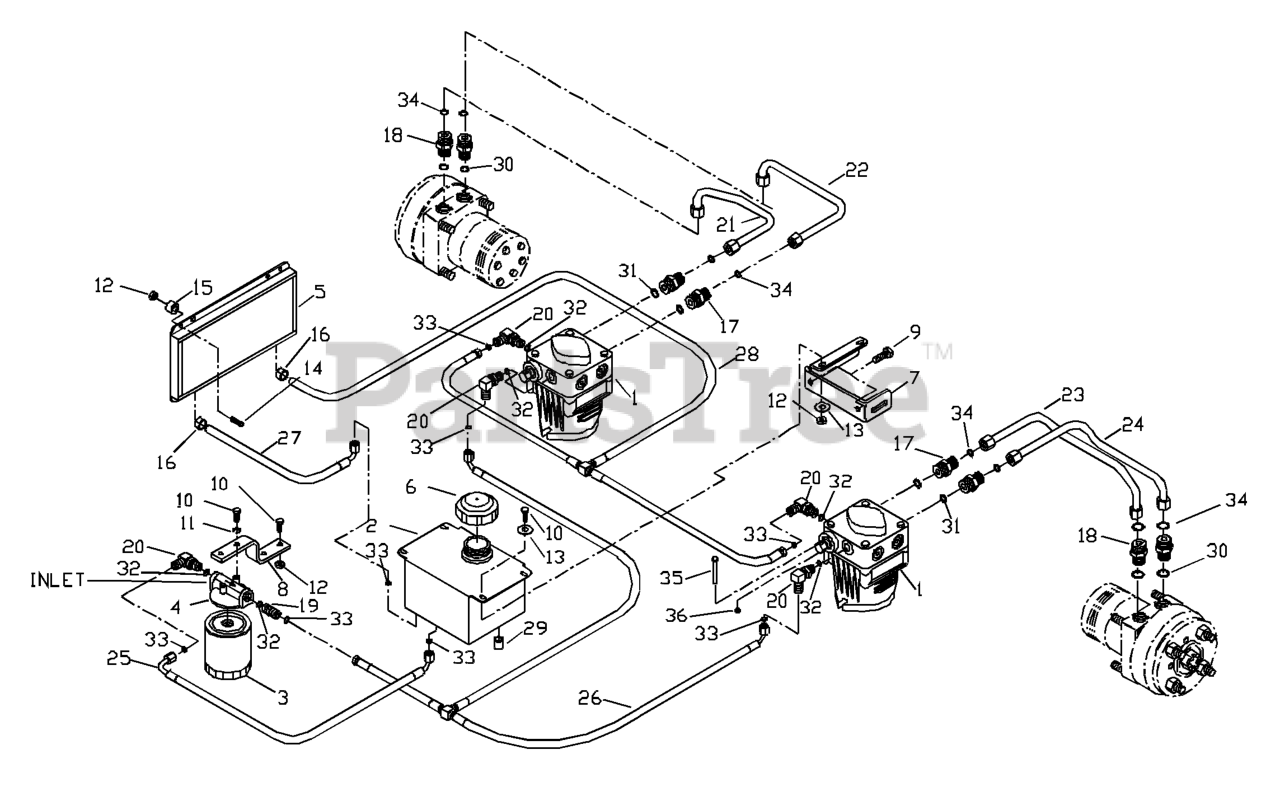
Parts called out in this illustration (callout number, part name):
1	PUMP
3	HYDRAULIC OIL FILTER
4	FILTER HEAD
6	HYDRAULIC CAP
7	TANK MOUNT LT
7	TANK MOUNT RT
8	FILTER MOUNT
9	HCS 5/16C X 3/4
10	HCS 1/4C X 3/4 HCS
11	LOCKWASHER 1/4"
12	NUT 1/4C CENTERLOCK
13	WASHER 1/4 FLAT
14	HCS 1/4-20.X
16	HOSE CLAMP T-1865
17	FITTING, STRAIGHT F6400-8-8-0
19	STRAIGHT FITG
20	ELBOW, F6801-6-6-0 90 DEGREE
21	RT. OUTSIDE TUBE
22	RT. INSIDE TUBE
23	LT.INSIDE TUBE
24	LT.OUTSIDE TUBE
29	NUT 9/16-18 JIC CAP
35	CLEVIS PIN
36	NUT PUSH
